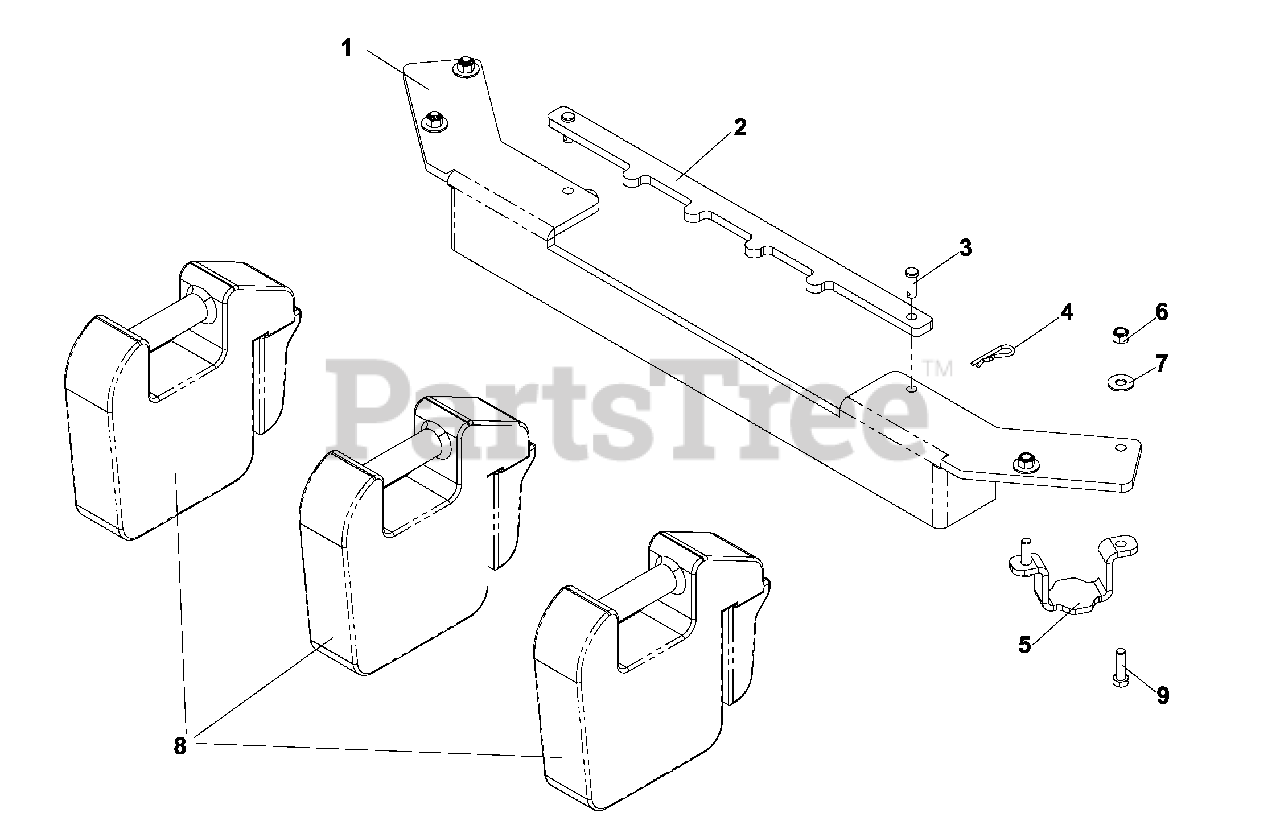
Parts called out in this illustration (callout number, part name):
1	FRONT WT BAR, BLACK
2	HOLD DOWN, WEIGHT BAR
3	CLEVIS PIN
4	RETAINER SPRING
5	WEIGHT KEEPER
6	NUT 3/8-16 NYLOC
7	WASHER 3/8 FLAT
8	FRT WEIGHT CAST PZ DFS
9	HCS 3/8C X 1 1/4 GR5
